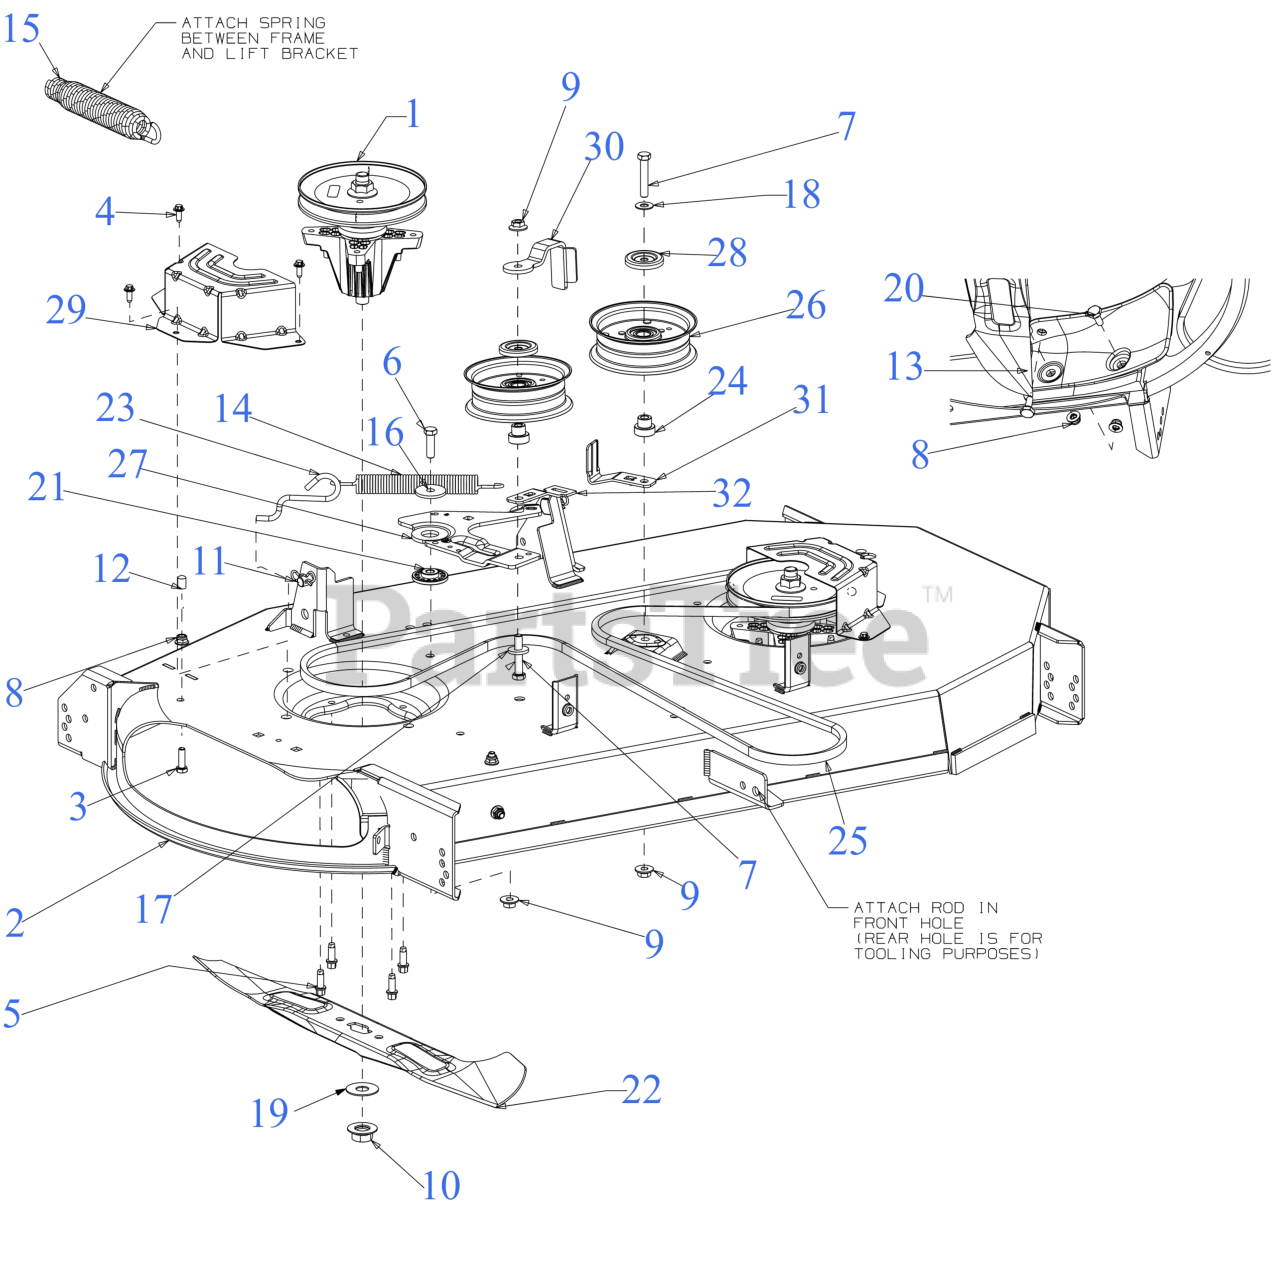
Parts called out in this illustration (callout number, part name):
1	SPINDLE ASSEMBLY (6.93 DIA)
2	46" FAB DECK SHELL
3	SCREW 5/16-18 x 1.0 GR5
4	SCREW M6-1 x .625
5	SCREW 5/16-18 x .875
6	SCREW 3/8-16 x 1.25 GR5
7	SCREW 3/8-16 x 2.0
7	SCREW 3/8-16 x 2.0 GR 8
8	FLANGE LOCK NUT 5/16-18
9	FLANGE LOCK NUT
10	HEX FLANGE NUT 5/8-18 GR5
11	BOW TIE COTTER PIN
13	DISCHARGE BAFFLE
14	EXTENSION SPRING
15	LIFT ASSIST SPRING (LARGE)
16	FLAT WASHER .390x1.500x.134
17	FLAT WASHER .385 x 1.00 x .135
18	FLAT WASHER .401X.88
19	FLAT WASHER .635X1.585X.062 HDN
20	SHOULDER SCREW
21	SHOULDER SPACER
22	23.25" BLADE (2IN1) (S SHAPE CENTER HOLE)
22	Cub Cadet 46" HI LIFT BLADE SET (S SHAPE CENTER HOLE) (-05510)
22	23.25" XTREME BLADE (2IN1) (S SHAPE CENTER HOLE)
22	Cub Cadet 46" XTREME BLADE SET (S SHAPE CENTER HOLE) ( -05510-X)
22	23.25" LOW LIFT BLADE (S SHAPE CENTER HOLE)
22	Cub Cadet 46" LOW LIFT BLADE SET (S SHAPE CENTER HOLE) (-05510-L)
23	DECK SPRING HOOK
24	SHOULDER SPACER
25	V-BELT A SECX108.3
25	Cub Cadet 46" DECK BELT (-05087A)
25	Troy-Bilt 46" DECK BELT
26	IDLER PULLEY 4.50" DIA
27	46" IDLER PIVOT BRACKET
28	IDLER PULLEY CAP
30	BELT KEEPER
